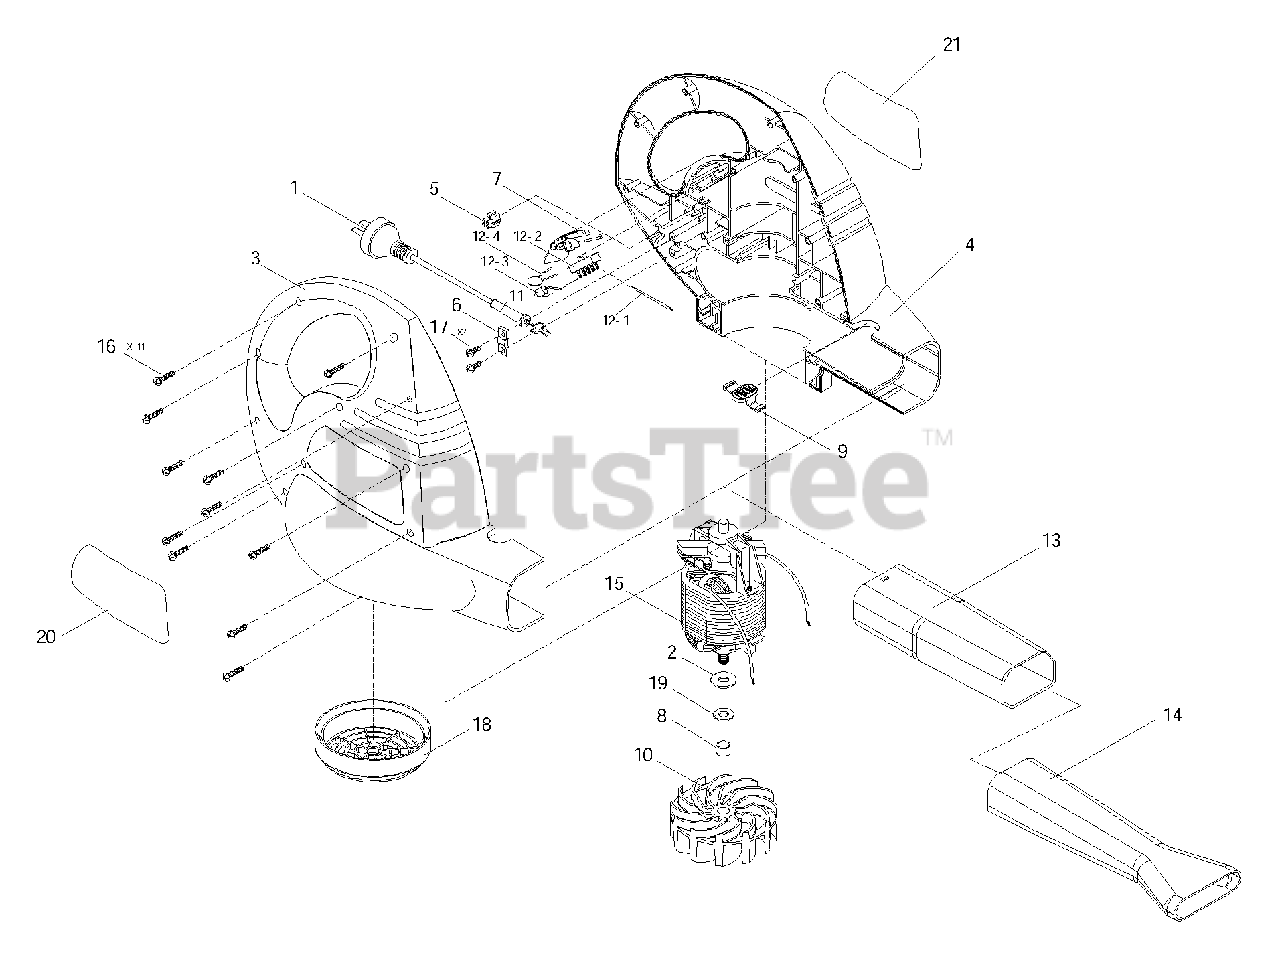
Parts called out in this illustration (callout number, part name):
1	POWER CORD
3	HOUSING (L)
4	HOUSING (R)
5	TERMINAL BLOCK
6	STRAIN RELIEF
8	SHAFT SLEEVE
11	CORD GUARD
18	SAFETY COVER
